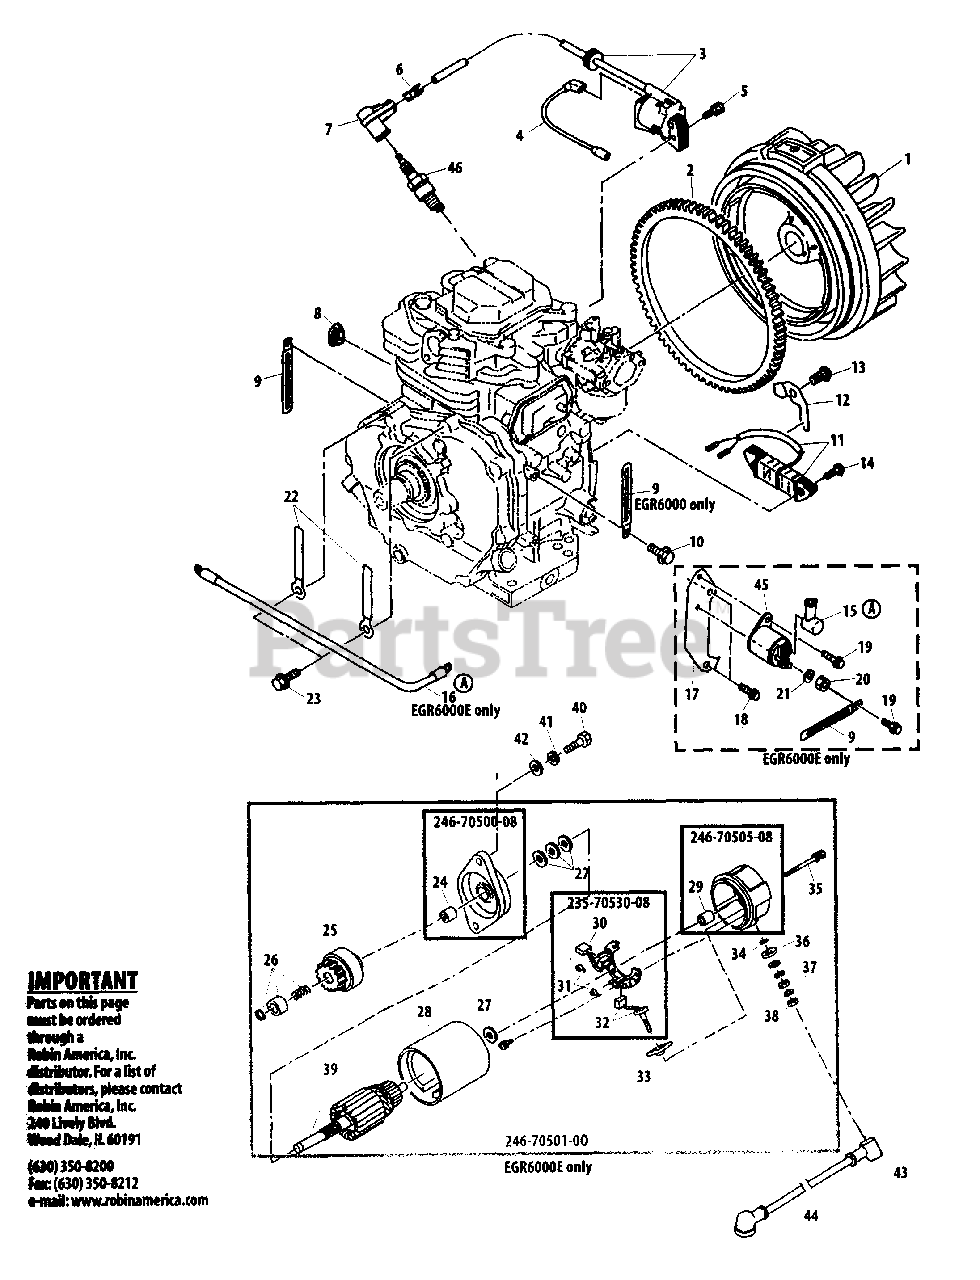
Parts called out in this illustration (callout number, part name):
1	FLYWHEEL
2	RING GEAR
3	IGNITION COIL ASSY
4	WIRE
5	BOLT
6	PLUG TERMINAL
7	CAP, SPARK PLUG
8	GROMMET
9	CLAMP
10	BOLT - FLANGE
11	CHARGE COIL ASSY
12	CLAMP
13	SCREW
14	SCREW
15	WIRE CASING
16	WIRE
17	BRACKET
18	BOLT - FLANGE
19	BOLT
20	NUT
21	LOCKWASHER
22	CLAMP
24	BUSHING
25	GEAR - SHAFT
26	STOPPER SET PINION
27	WASHER
28	FIELD HOUSING ASSY
29	BUSHING
30	BRUSH - ( + )
31	SPRING
32	BRUSH - ( - )
33	BRUSH
34	O-RING
35	BOLT
36	INSULATOR, BRUSH
37	LOCKWASHER
38	NUT
39	ARMATURE ASSY
40	BOLT
41	LOCKWASHER
42	WASHER
43	WIRE CASING
44	BATTERY CABLE - POSITIVE
45	SWITCH
46	SPARK PLUG -- BR-6ES
235-70530-08	HOLDER ASSY
246-70500-08	FRONT COVER ASSY
246-70505-08	REAR COVER ASSY
